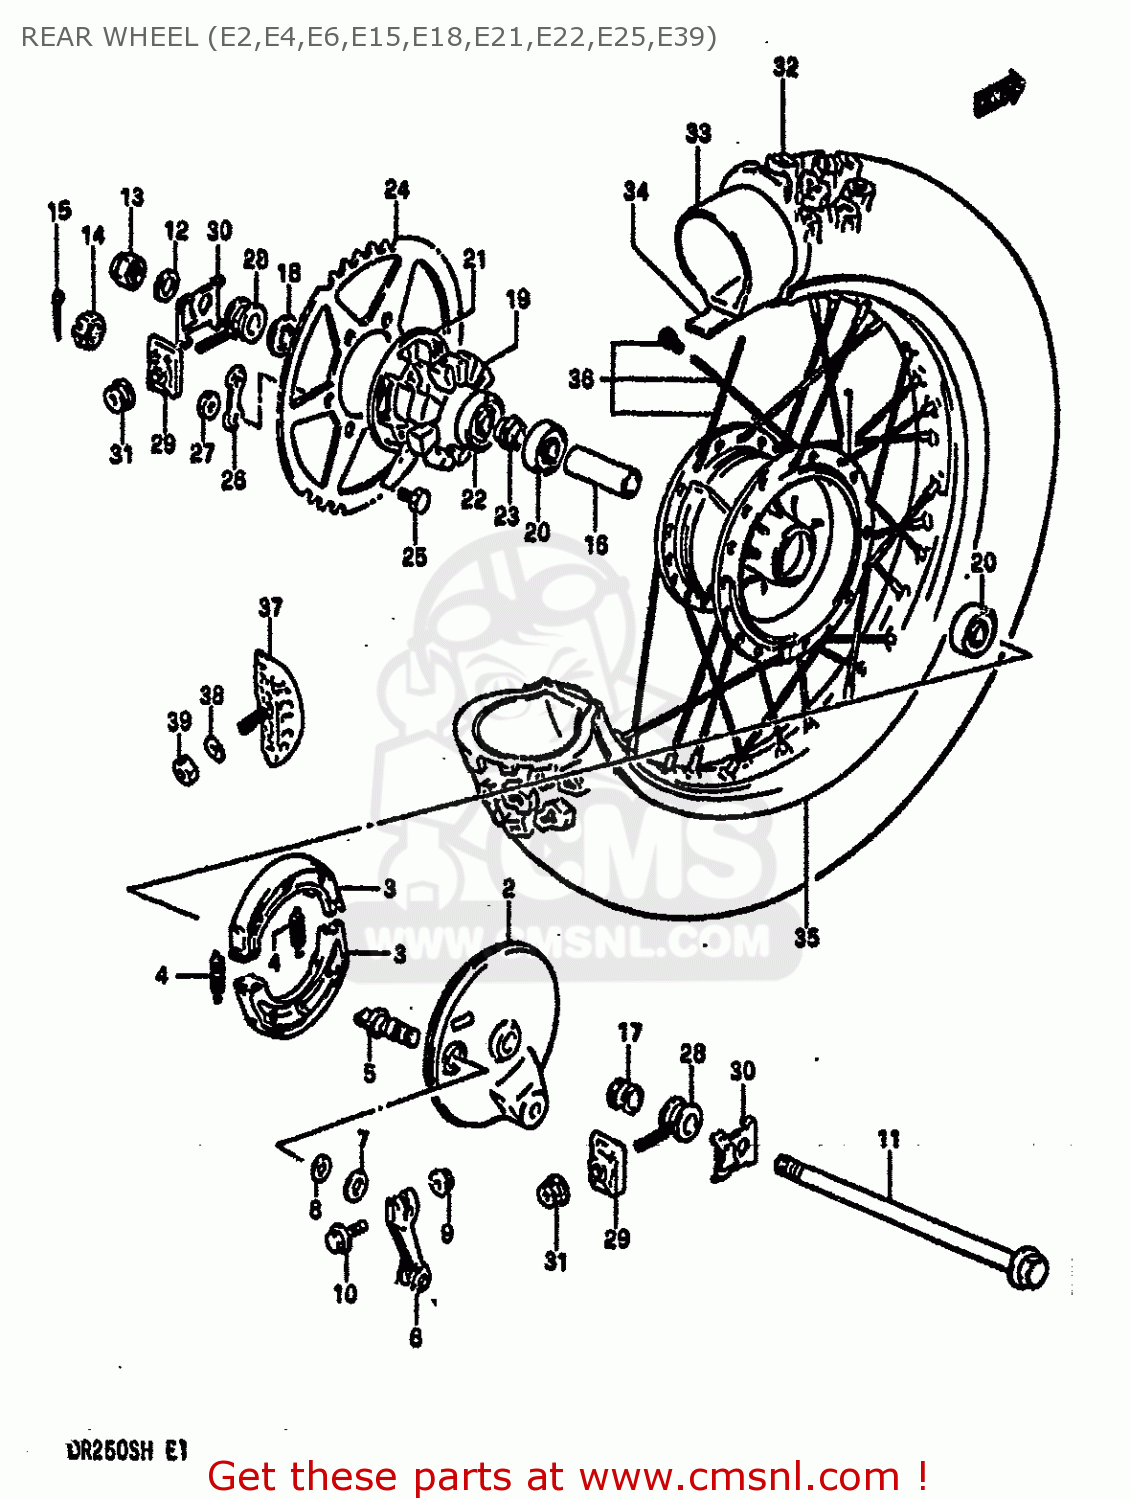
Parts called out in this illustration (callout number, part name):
1	DRUM,REAR HUB
2	PANEL,REAR HUB
3	SHOE,BRAKE
4	SPRING(L:34)
5	CAM,FRONT BRAKE
6	LEVER,REAR BRAKE CAM
7	WASHER (14.5X22X1.6)
8	O-RING (D:2.4 ID:13.8)
9	NUT
10	BOLT 6X35
11	AXLE,REAR
12	WASHER
13	NUT
14	NUT
15	PIN,COTTER
16	SPACER,REAR HUB BEARING
17	SPACER,REAR AXLE,RIGHT
18	SPACER,REAR AXLE,LEFT
19	ABSORBER,RR SHOCK
20	BEARING
21	DRUM,REAR SPROCKET MOUNT
22	BEARING
23	SPACER,REAR HUB BEARING
24	SPROCKET,RR(NT:42)
25	BOLT
26	WASHER
27	NUT
28	ADJUSTER,CHAIN
29	PLATE,CHAIN ADJUSTER
30	WASHER,CHAIN ADJUSTER GUIDE
31	NUT
32	TIRE, REAR (4.00X18)
33	TUBE,INNER
34	PROTECTOR,WHEEL,INNER
35	RIM,WHEEL (215X18AL) (GOLD)
36	SPOKE ASSY, REAR
37	STOPPER,BEAD
38	WASHER
39	NUT
